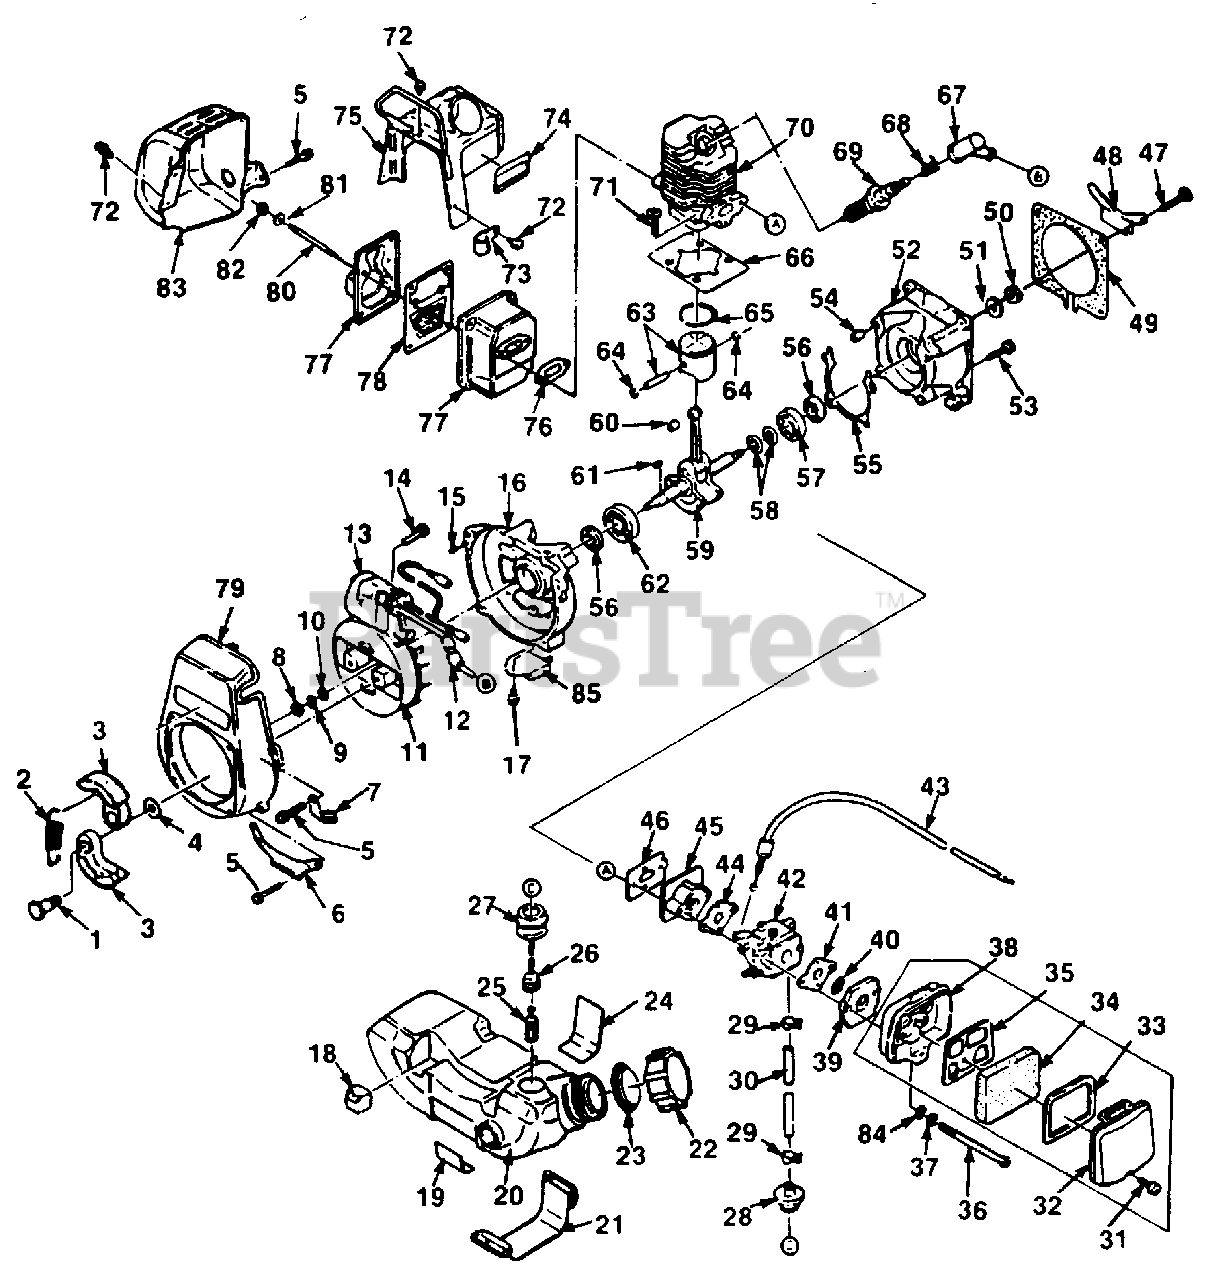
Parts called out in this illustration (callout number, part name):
1	PIN- Clutch
2	SPRING- Clutch
3	SHOE- Clutch
5	SCREW- (M5 x 16)
6	BRACKET- Tank
7	BRACKET- Cable
8	NUT- (M6 mm)
9	WASHER- Spring
11	FLYWHEEL
13	COIL- Ignition
14	BOLT- (M5 x 24)
15	PIN- Dowel
16	CRANKCASE
17	SCREW- (M4 x 8)
20	FUEL TANK (Incl. item #22 & 23)
21	BAND- Tank
22	CAP- Tank
23	BREATHER
25	FILTER ASSEMBLY
31	SCREW (M4 x 14)
32	CAP- Air cleaner
33	PLATE- Air Cleaner
35	PLATE- Air cleaner
37	WASHER- Spring
38	CASE- Air filter
42	CARBURETOR ASSEMBLY
43	CABLE- Throttle
45	INSULATOR
47	SCREW (M5 x 18)
48	BRACKET- Tank
50	NUT- (M6 MM)
51	WASHER- (M6)
52	CRANKCASE
54	PIN- Dowel
56	SEAL- Oil
57	BEARING- Ball (6000C3)
58	SHIM ASSEMBLY
59	CRANK SHAFT ASSEMBLY
60	BEARING- Plain
62	BEARING- Ball (6200C3)
63	PISTON ASSEMBLY
64	RING- Snap
65	RING- Piston
67	CAP- Plug
69	SPARK PLUG (DJ7Y)
70	CYLINDER
72	SCREW (M4 x 10)
77	MUFFLER ASSY
78	SPARK ARRESTOR
79	HOUSING- Fan
83	COVER- Muffler
